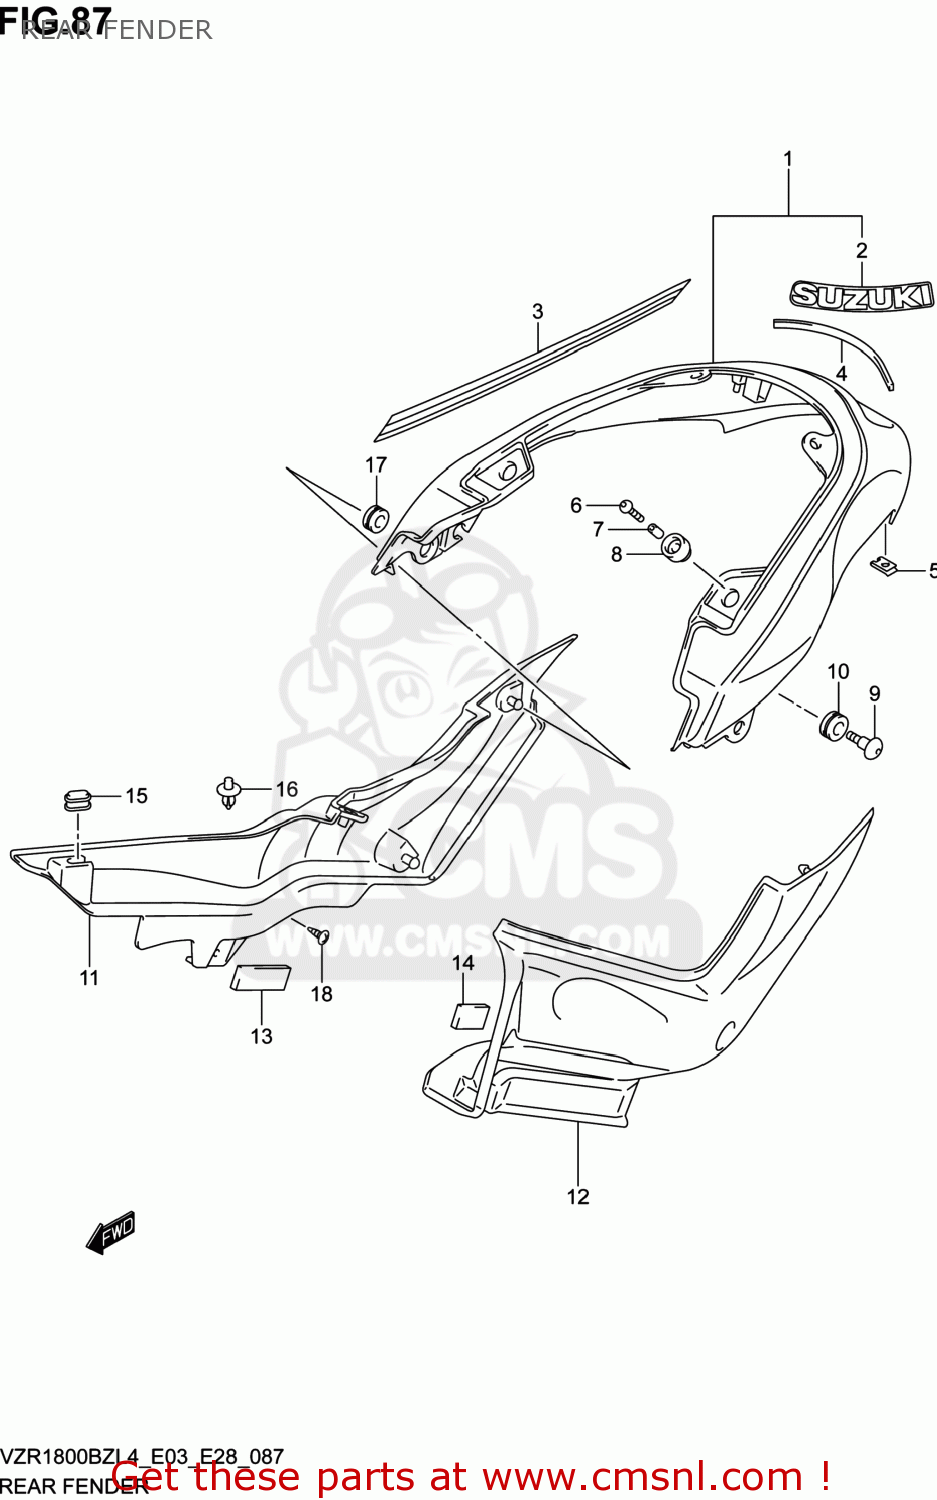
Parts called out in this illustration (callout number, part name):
1	FENDER,REAR
2	EMBLEM,SUZUKI
3	TAPE SET,REAR FENDER
4	CUSHION,RR FENDER RR COVER
5	NUT,COWL
6	SCREW(6X16)
7	SPACER(6.5X10X9.4)
8	CUSHION
9	BOLT(6X20)
10	CUSHION
11	COVER,RR FENDER,R
12	COVER,RR FENDER,L
13	CUSHION,FUEL PIPE
14	CUSHION,FRAME COVER
15	CUSHION,FUEL TANK COVER
16	CLIP(BLACK)
17	CUSHION
18	SCREW
